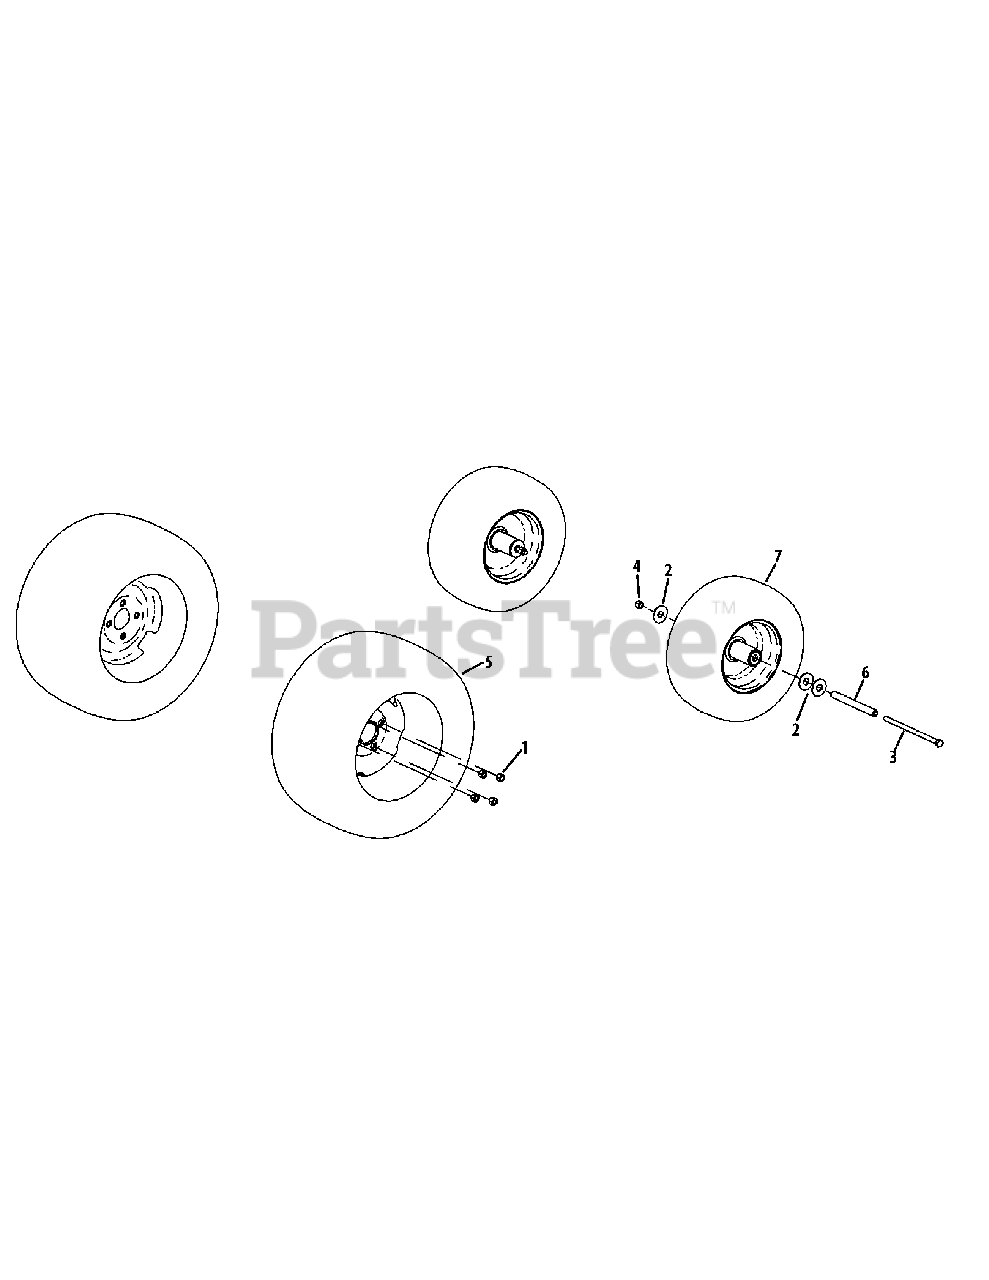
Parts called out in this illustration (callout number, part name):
1	Lug Nut, 1/2-20
2	Washer, .781 x 2.00 x .105
3	Hex Screw, 1/2-20 x 9.50
4	Nut, 1/2-20, Lock
5	Wheel Assembly, 24 x 12.00-12
5	Tire, 24 x 12.00-12, Turf Master
6	Spacer, .51 x .75 x 7.49
7	Front Wheel Assembly, 16 x 6.50-8
7	Tire, 16 x 6.50-8
